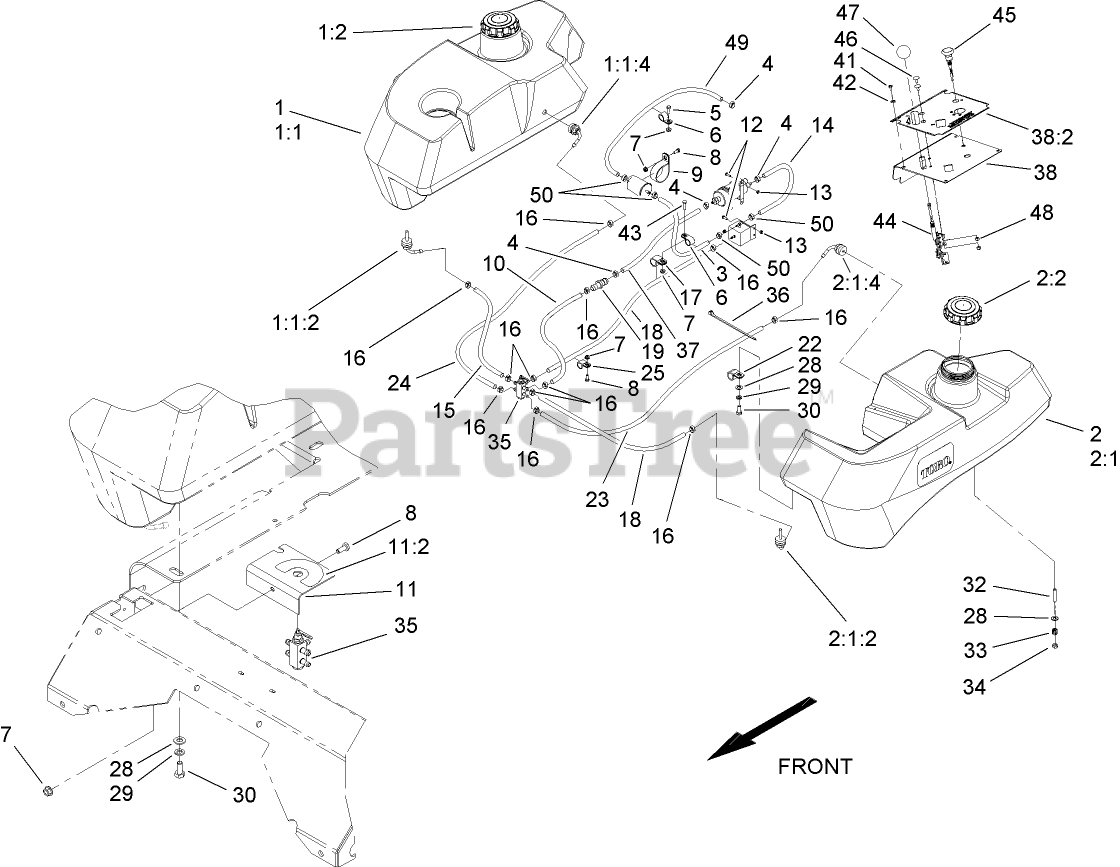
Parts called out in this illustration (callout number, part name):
1	RH FUEL TANK KIT ASM
1:1	TANK-FUEL, RH
1:1:2	FITTING-FUEL, BULKHEAD
1:1:4	Fitting-Fuel, Bulkhead
1:2	CAP-FUEL, GAS
2	LH FUEL TANK KIT ASM
2:1	TANK-FUEL, LH
2:1:2	FITTING-FUEL, BULKHEAD
2:1:4	Fitting-Fuel, Bulkhead
2:2	CAP-FUEL, GAS
3	HOSE, FUEL
4	CLAMP-HOSE, FUEL
5	SCREW-HH
6	CLIP-LOOM
7	NUT-HF
8	SCREW-HH
9	CLIP-LOOM
10	HOSE-FUEL
11	Fuel Valve Bracket Asm
11:2	DECAL-VALVE, FUEL
12	SCREW-PPH
13	NUT-LOCK, NI
14	Hose-Fuel
15	HOSE-FUEL
16	CLAMP-HOSE, FUEL
17	CLIP-LOOM
18	HOSE-FUEL
19	Connector
23	Hose-Fuel
24	Hose-Fuel
25	CLIP-LOOM
28	WASHER-PLAIN
29	WASHER-LOCK
30	SCREW-HH
33	SPRING-TANK, FUEL
34	NUT-LOCK, NI
35	VALVE-FUEL, DUAL FLOW
36	TIE-CABLE
37	HOSE-FUEL
38	CONTROL PANEL ASM
38:2	DECAL-PANEL, CONTROL
41	SCREW-PPH
42	WASHER-SPRING
43	SCREW-HH
44	CABLE-THROTTLE
45	CONTROL-CHOKE, PUSH / PULL
46	BOLT-CARR
47	KNOB-BALL
48	NUT-LOCK, NI
49	Hose-Fuel
